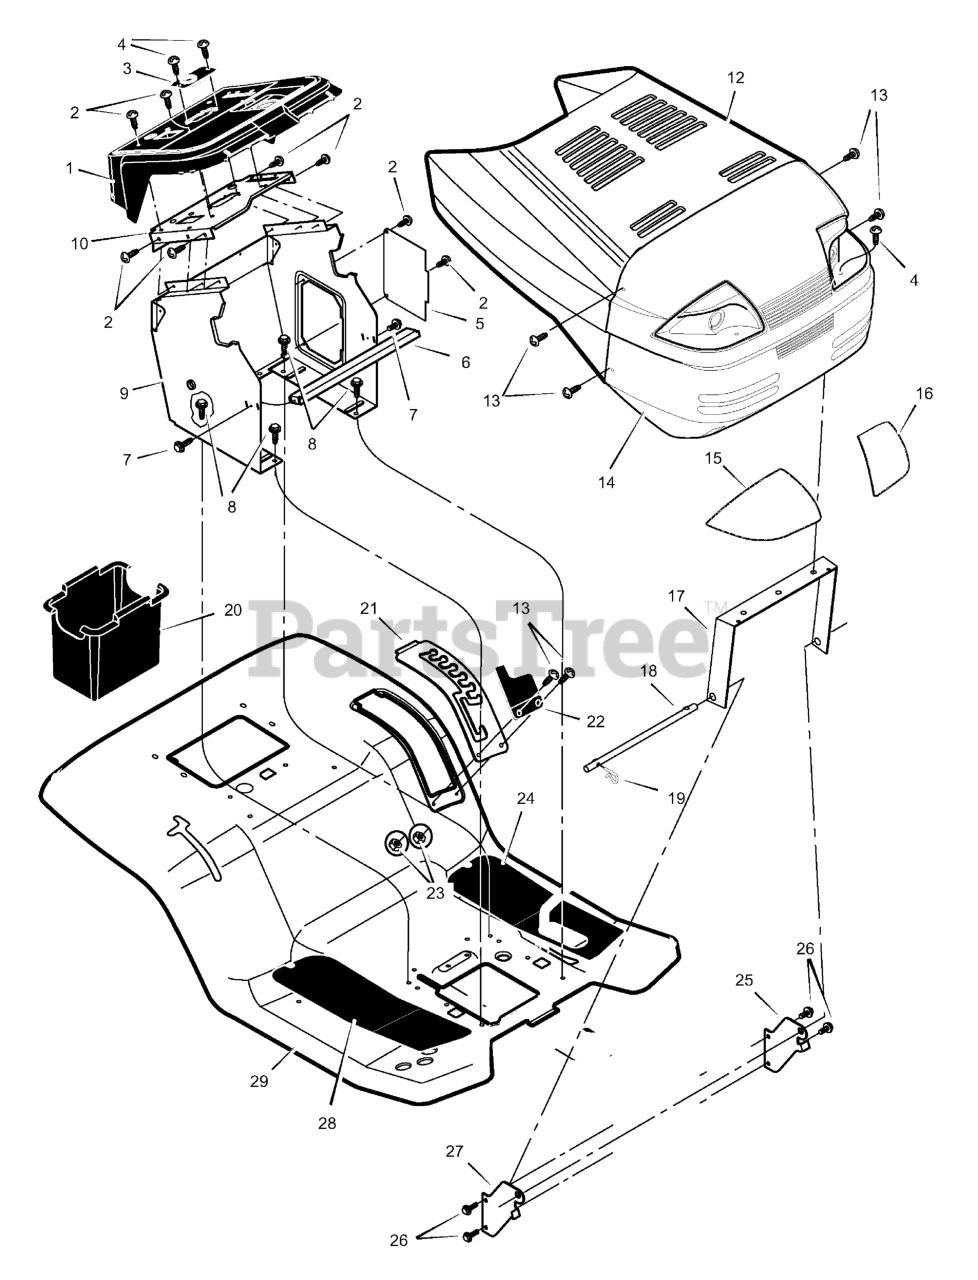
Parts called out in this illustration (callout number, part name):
2	Screw
3	Bearing, Upper Steering
5	Panel, Side Access
6	Channel, Support
9	Support, Dash
10	Plate, Dash
12	Hood
13	Bolt, Shoulder
14	Grille
15	Lens, Right
16	Lens, Left
17	Brace, Grille
18	Rod, Pivot
19	Pin, Hair
20	Container, Battery
21	Plate, Lift Detent
24	Mat, Left
25	Support, Left Grille
27	Support, Right Grille
28	Mat, Right
29	Deck, Seat
30	Decal, Left Hood
